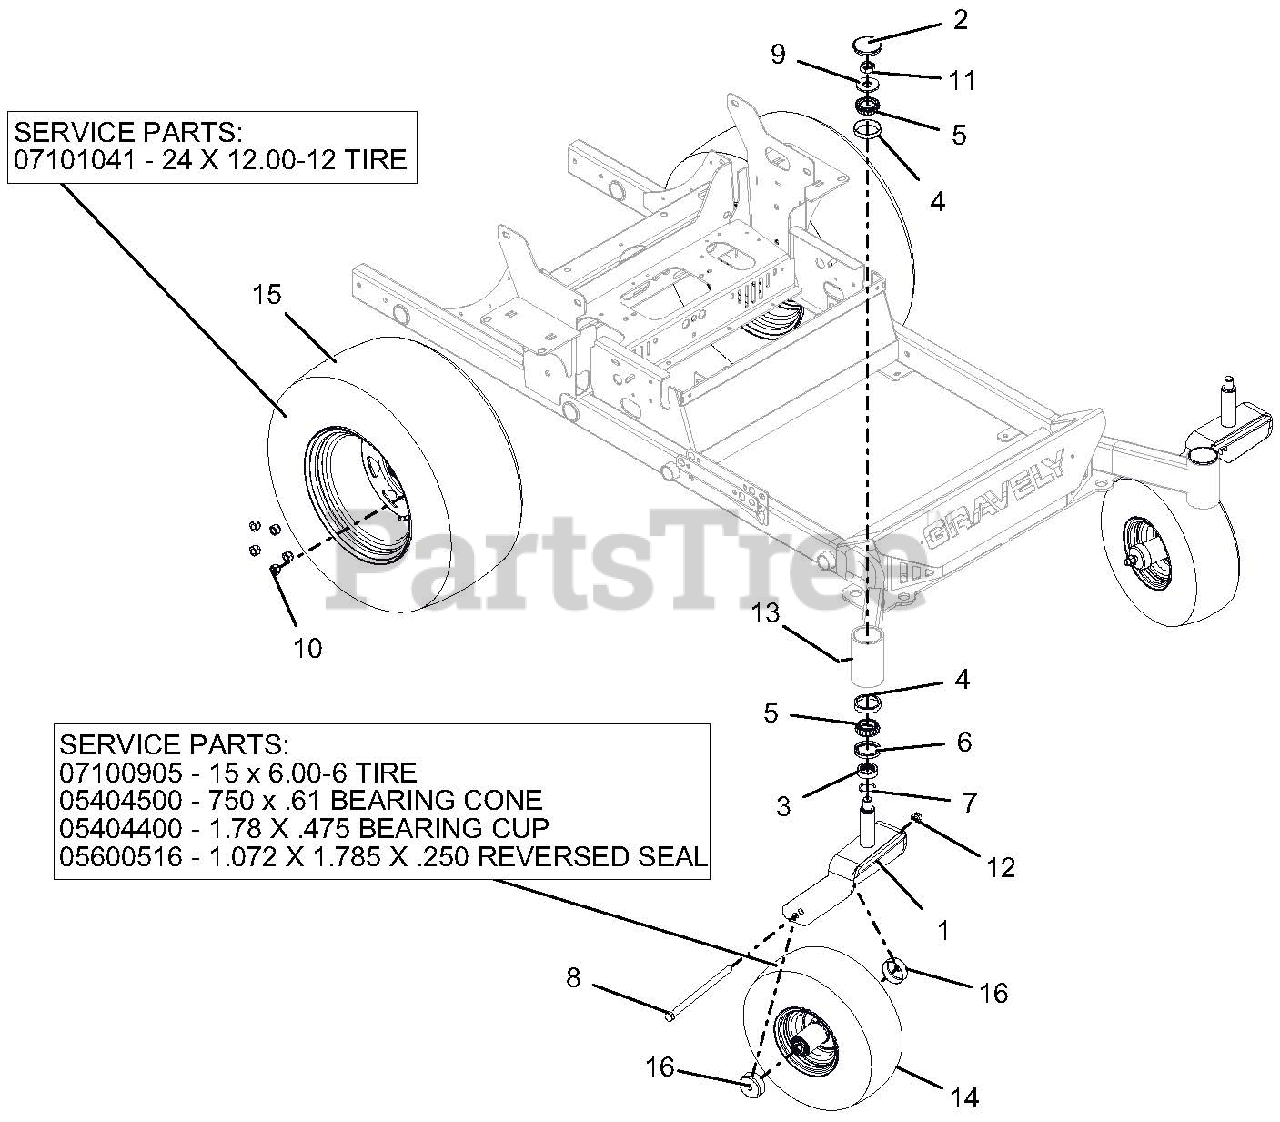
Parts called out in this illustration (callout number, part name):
1	WMT, CASTER FORK - RED
2	CAP, DUST
3	SPCR, FRONT CASTER FORK
4	BRG, CUP 2.328 X .465
5	BRG, CONE 1.250 X .660
6	SEAL, OIL 1.75 X 2.332 X .312
7	O-RING, .139 W X 1.234 ID
8	BLT-HEX .50-13X9.00 GR5 YWZC
9	WSHR-FL-STL.812X2.00X.148YWZC
10	NUT, LUG .500-13
11	NUT-LK-TOP-JAM .75-16 YWZC
12	NUT, LK-TOP-FLG .50-13 YWZC
13	FITTING, .250-28 FLUSH MOUNT GREASE
14	TIRE/WHEEL, 15 X 6.00-6 SMOOTH
14	15 X 6.00-6 TIRE
14	750 X .61 BEARING CONE
14	1.78 X .475 BEARING CUP
14	1.072 X 1.785 X .250 REVERSED SEAL
15	TIRE/WHEEL, ASM 24 x 12-12
15	24 X 12.00-12 TIRE
16	SHIELD, WHEEL BEARING
